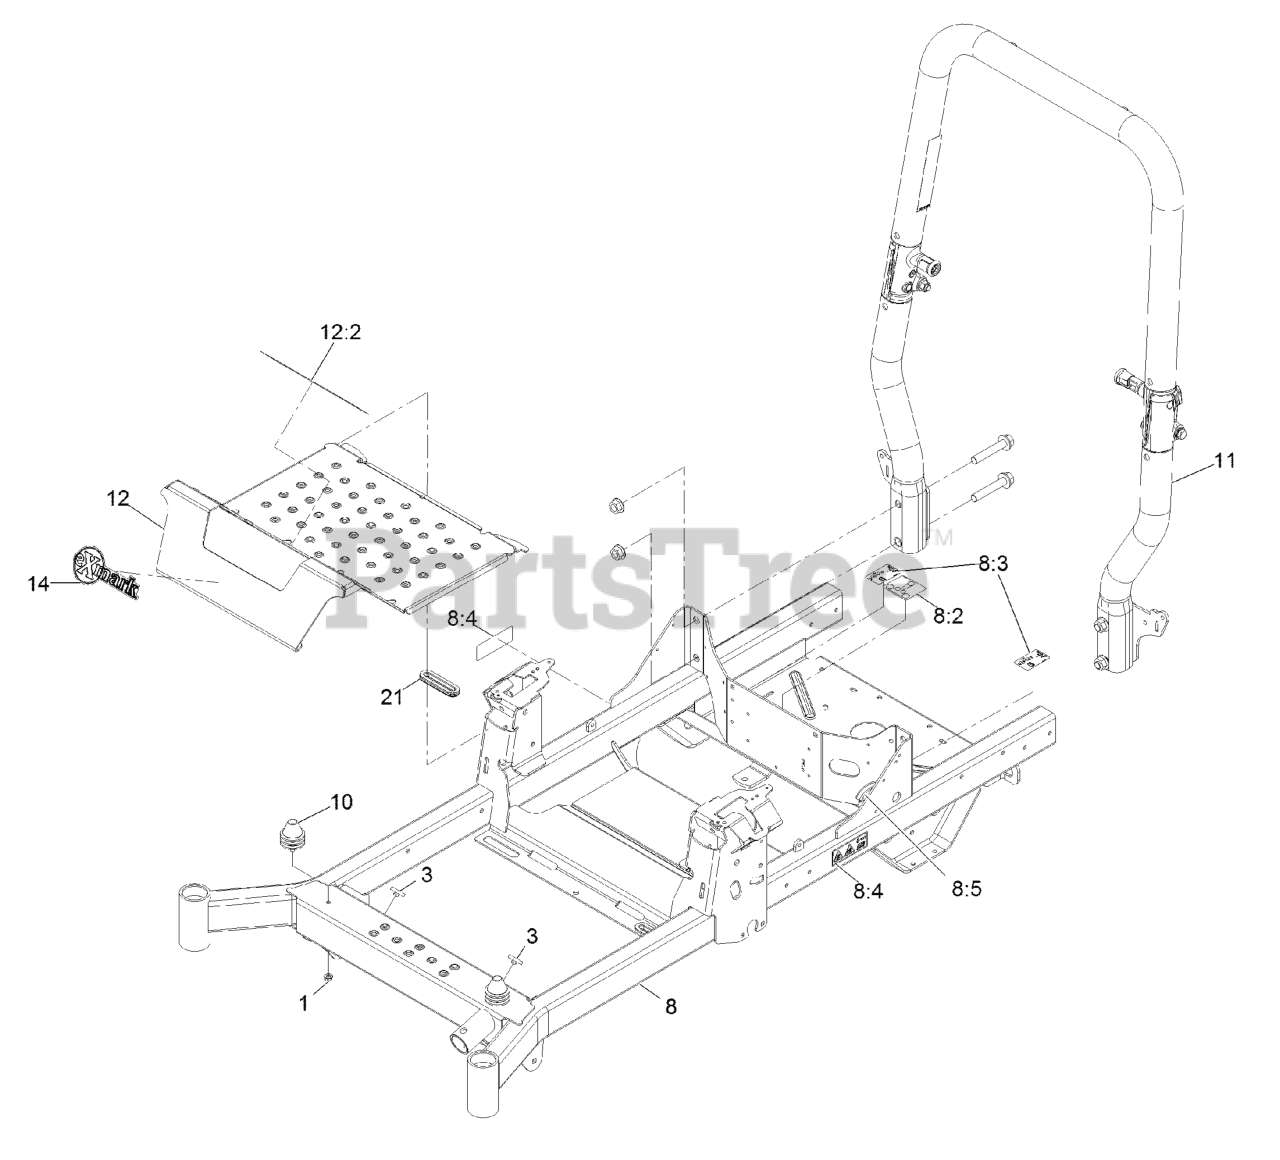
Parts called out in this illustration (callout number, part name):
1	NUT-HF, NI
2	BEARING-BALL
3	BUMPER-PUSH-IN, RUBBER
4	CAP-GREASE
5	WHEEL AND TIRE ASM
5:1	WHEEL-12X7, 8 SPOKE 4 ON
5:2	TIRE
5:3	Stem-Valve
8	FRAME ASM
8:2	DECAL-ROUTING, BELT
8:3	DECAL-RELEASE, DRIVE
8:4	DECAL-WARNING
8:5	STRIP-SEAL
9	ASM-Front Caster W/Fork
10	ISOLATOR
11	ASM-ROPS TAPERED
12	PAN-FLOOR
12:2	DECAL-DANGER
14	DECAL-EXMARK LOGO
15	NUT-LUG
17	SCREW-HHF
18	WASHER-FLAT
21	GROMMET-RUBBER
